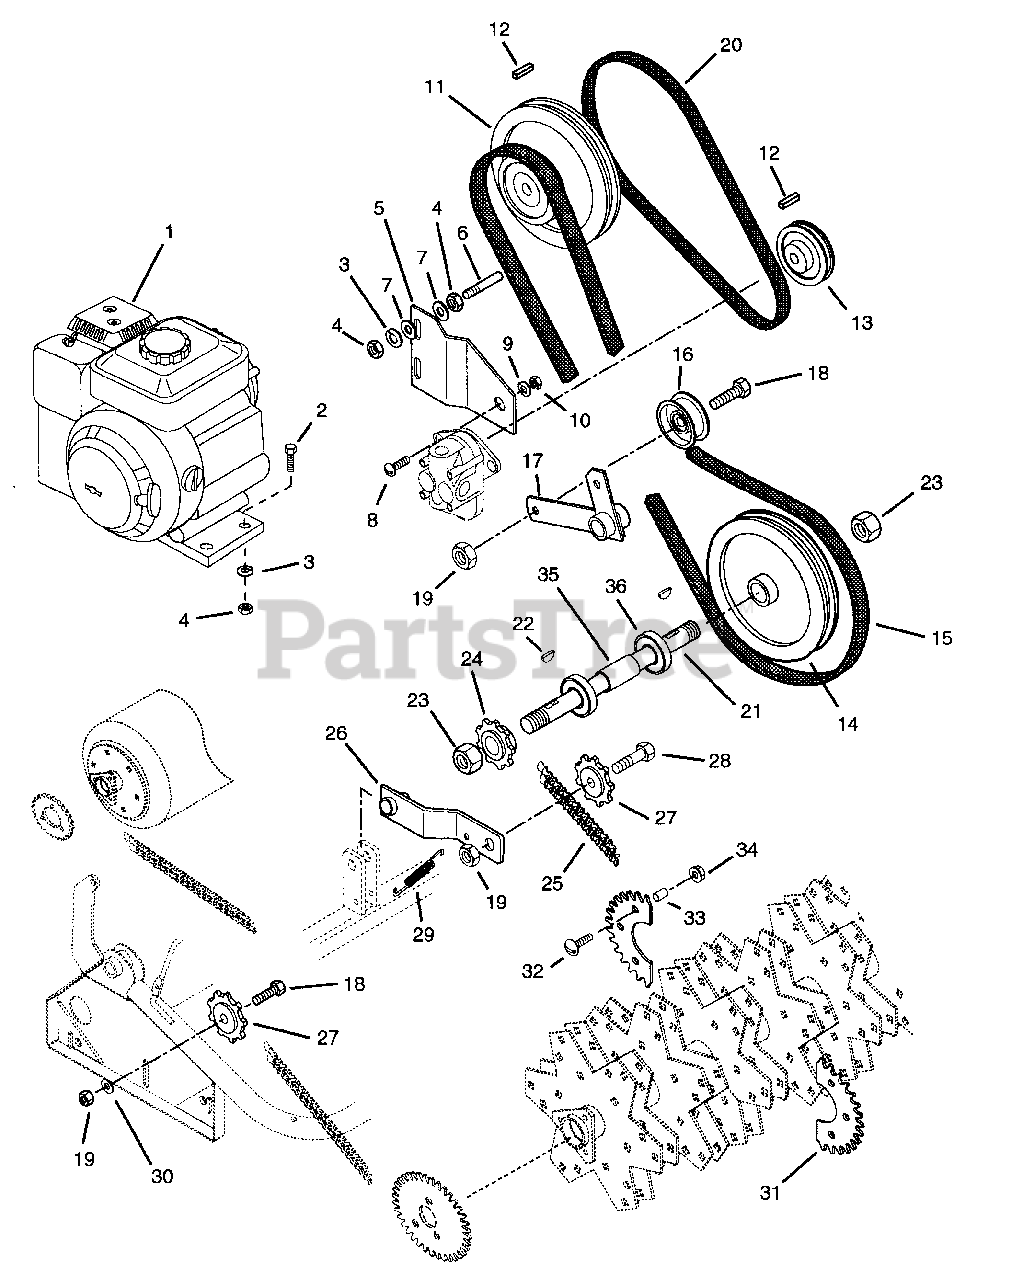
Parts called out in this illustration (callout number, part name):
1	Engine, Honda
2	Bolt-Hex .31-18 x 1.50 Grade 5
3	Washer-Lock .313 x .078
4	Nut-Hex .312-18 Grade 2
5	Belt Aligner
6	Belt Alignment Bolt
7	Washer-Flat-Steel .38 x .875 x .083
8	Bolt-Round Head Square Neck .38-16 x 1.2Grade 5
9	Washer-Lock .375 x .094
10	Nut-Hex .375-16 Grade 2
11	Pulley Weldment
12	Keystock .188 x 1.25
13	Hydraulic Pulley Weldment
14	Driver Pulley Weldment
15	V-Belt B54
16	Belt Tightener Pulley
17	Idler Weldment
18	Bolt Hex .50-13 x 1.75
19	Nut-Locking Unitorque .50
20	V-Belt B36
21	Counter Shaft
22	Key-Woodruff .188 x .750
23	Nut-Locking 2-Way .75
24	Sprocket w/Hub
25	Chain #40
26	Chain Tightener Weldment
27	Idler Sprocket 18 Tooth
28	Bolt-Hex .50-13 x 2.00 Grade 5
29	Spring-Tension
30	Washer-Flat-Steel .531 x 1.062 x .095
31	Split Sprocket
32	Bolt-Round Head Square Neck .312 x 2.50
33	Spacer-Split Sprocket
34	Nut-Locking .312-18
35	Spacer-Cross Shaft
36	Bearing-Schultz
